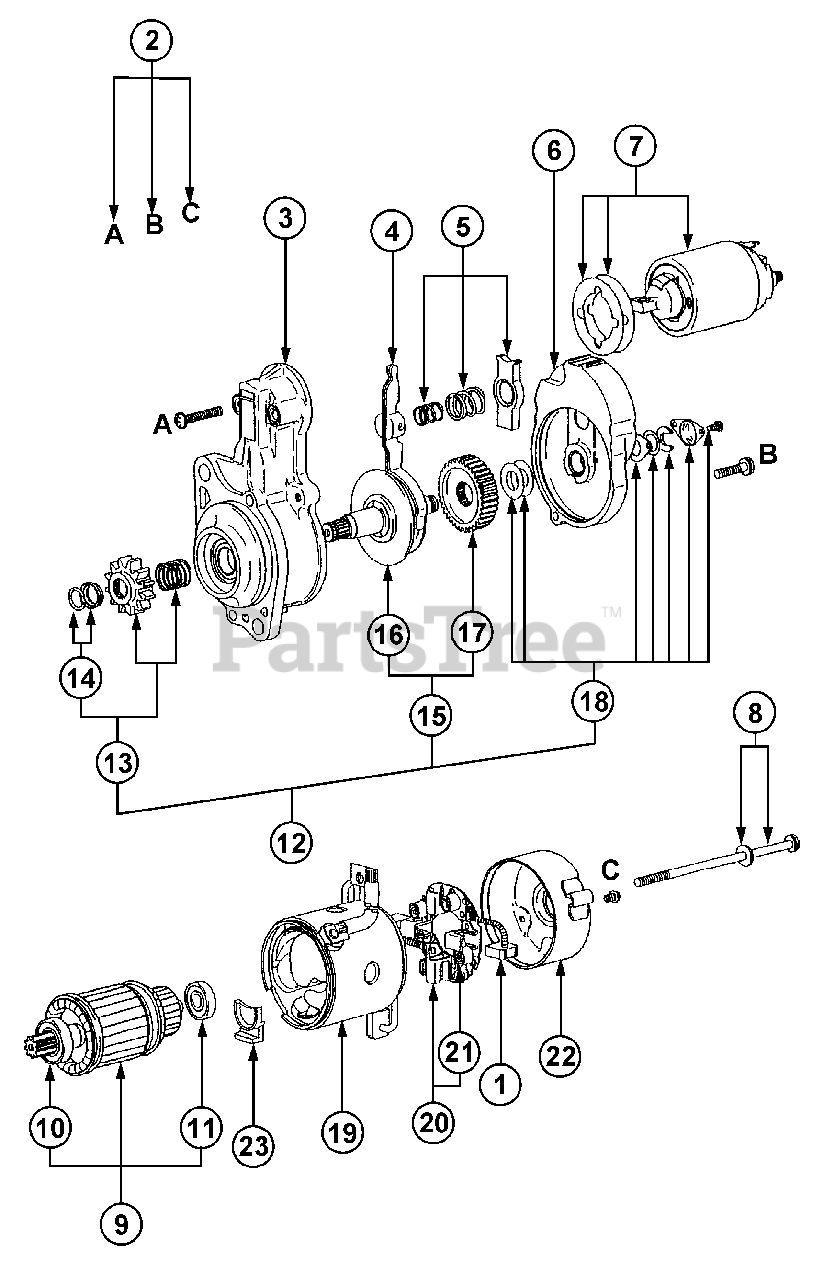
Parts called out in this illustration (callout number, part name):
1	Brush
3	Bracket Assy, Front
4	Lever Assy
5	Spring Set
6	Bracket Assy, Center
9	Armature Set
10	Bearing, Front
11	Bearing, Rear
16	Shaft Assy, Pinion
20	Holder Assy
21	Spring, Brush
22	Bracket Assy, Rear
